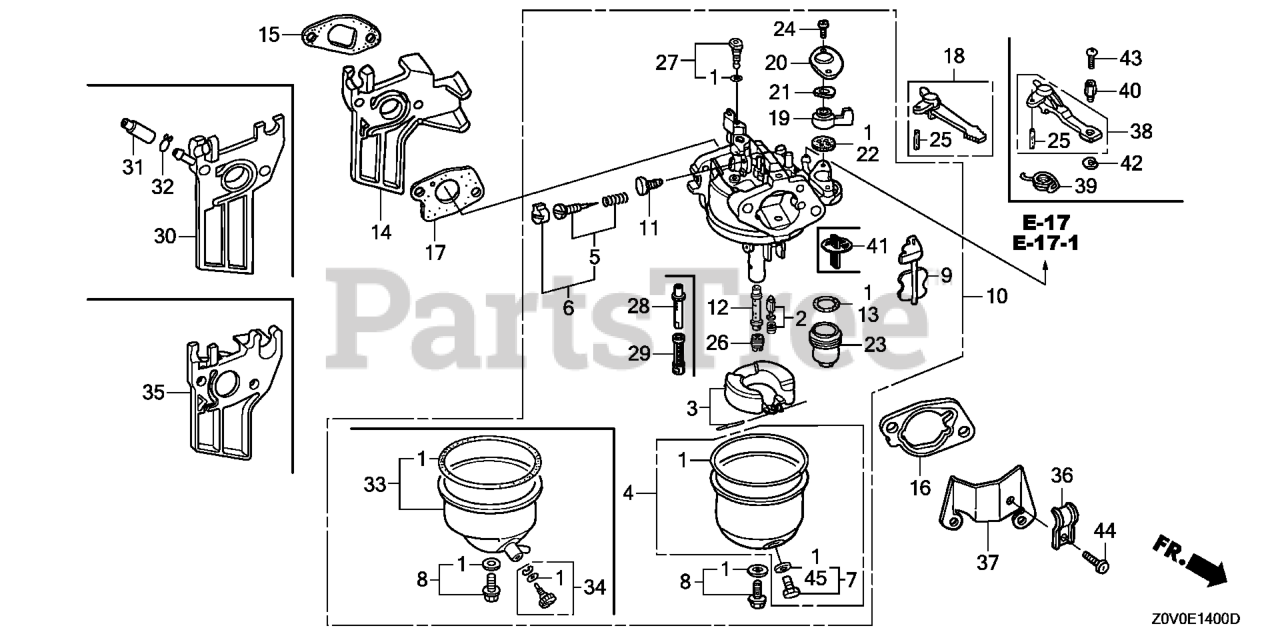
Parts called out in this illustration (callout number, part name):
1	GASKET SET
2	VALVE SET, FLOAT (CARBURETOR NO.) (SEAT NOT INCLUDED)
3	FLOAT SET
4	CHAMBER SET, FLOAT
5	SCREW SET (CARBURETOR NO.)
7	SCREW SET, DRAIN
8	SCREW SET (CARBURETOR NO.)
9	CHOKE SET (CARBURETOR NO.)
10	CARBURETOR ASSY. (BE59Q C)
11	SCREW, THROTTLE STOP
12	NOZZLE, MAIN (CARBURETOR NO.)
13	GASKET, FUEL STRAINER CUP
15	GASKET, INSULATOR
16	SPACER, CARBURETOR
17	GASKET, CARBURETOR
18	LEVER, CHOKE (STD)
19	LEVER, VALVE
20	PLATE, LEVER SETTING (CARBURETOR NO.)
21	SPRING, PETCOCK LEVER (CARBURETOR NO.)
22	GASKET, VALVE
23	CUP, FUEL STRAINER
24	SCREW, PAN (3X6)
25	PIN, SPRING (2X12)
26	JET, MAIN (#72) (CARBURETOR NO.)
26	JET, MAIN (#70)
26	JET, MAIN (#75) (CARBURETOR NO.)
27	JET SET, PILOT (#38)
35	INSULATOR, CARBURETOR
41	FILTER, CUP (CARBURETOR NO.)
45	WASHER, PLAIN (6.2X10.7 DRAIN) (CARBURETOR NO.)
